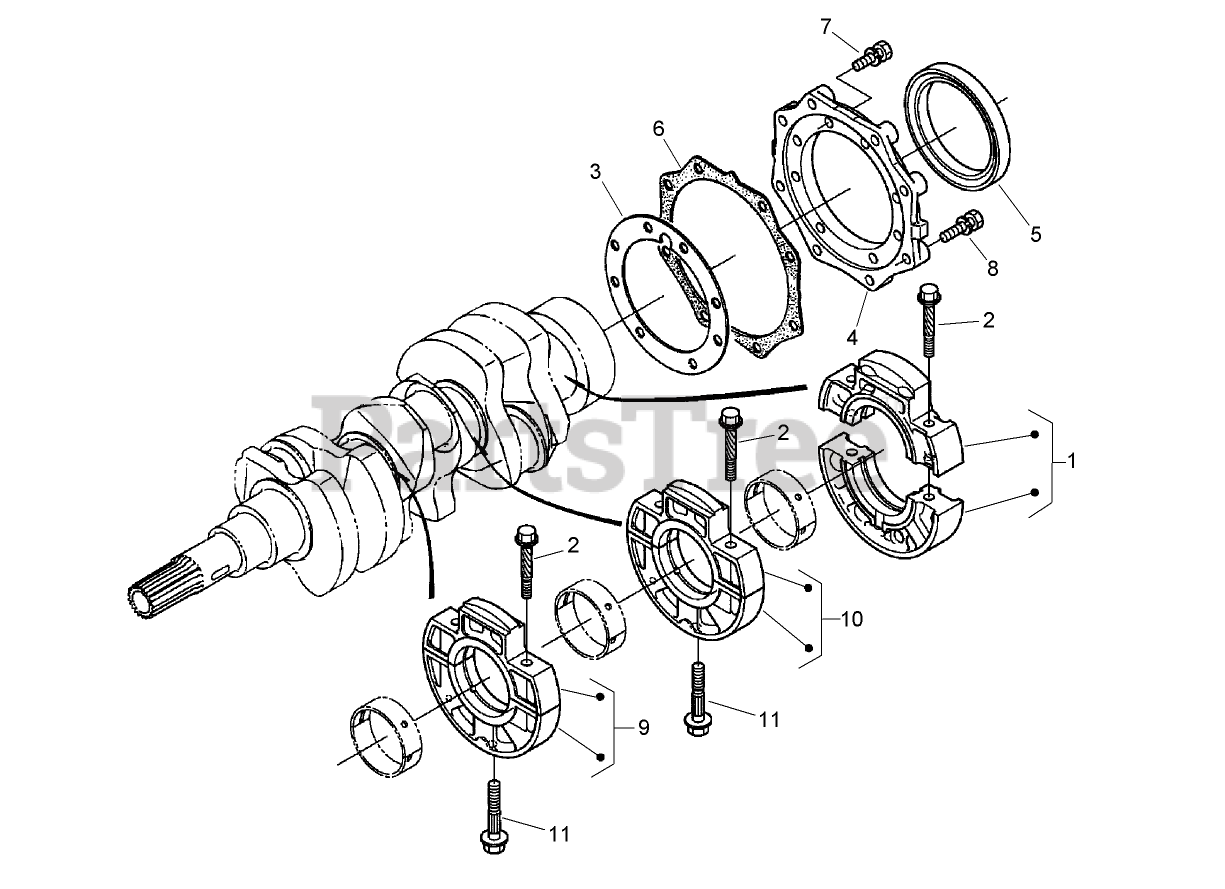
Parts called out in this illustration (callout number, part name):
1	MAIN BEARING CASE ASM
2	BOLT-CASE, BEARING
3	GASKET-CASE, BEARING
4	COVER-CASE, BEARING
5	SEAL-OIL
6	GASKET-COVER, CASE
9	MAIN BEARING CASE ASM
10	MAIN BEARING CASE ASM
11	BOLT-CASE, BEARING
